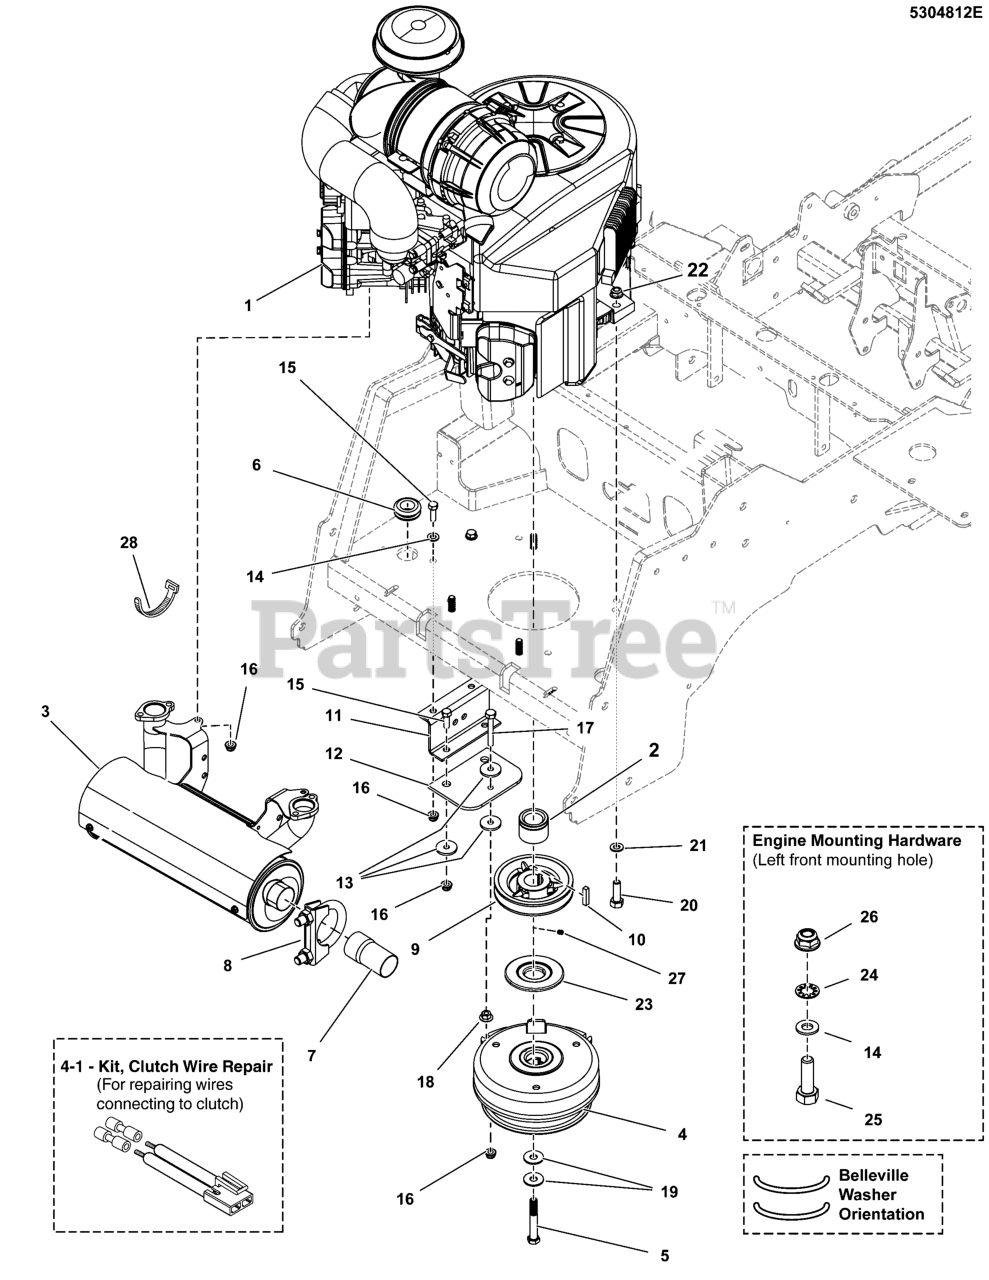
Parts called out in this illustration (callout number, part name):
2	SPACER, 1.13 X 1.75 X 1.35, CZ
3	MUFFLER (Purchase from Engine Manufacturer)
4	CLUTCH, 250 FT-LBS, WATER GUARD
4-1	KIT, CLUTCH WIRE REPAIR
5	BOLT, CRANKSHAFT, 7/16-20 X 3-1/4, GD 8
6	GROMMET, 7/8"ID, 1/4" THICK STK
7	TAIL PIPE EXTENTION, 1.78"ID X 5" LG
8	CLAMP, TAILPIPE, 1-7/8"
9	PULLEY, 4.75 OD X 1-1/8 BORE, BC-48
10	KEY, 1/4 SQ X 1-1/4
11	ANCHOR, CLUTCH, IS600-IS700 - BLK
12	CLUTCH ANCHOR PAD
13	WASHER, .34 X 1.25 X 10 GA
14	WASHER, 5/16" SAE
15	BOLT, 5/16-18 X 1 GD5 CZ
16	NUT, 5/16-18 HEX NYLOCK FLANGE
17	BOLT, 5/16-18 X 2-1/4 TFL, GD5 YZ
18	NUT, 5/16-18 HEX SERRATED FLANGE (LARGE)
19	BELLEVILLE WASHER 1.1875 X .442 X .089
20	BOLT, 3/8-16 X 1-3/4" GD5 CZ
21	WASHER, 3/8 SAE
22	NUT, 3/8 - 16 HEX NYLOCK FLANGE
23	WATER GUARD, WARNER C 250 FT-LBS CLUTCH
24	WASHER, 5/16 INT. TOOTH LOCK
25	BOLT, 5/16-24 X 1-3/4, GD8, PHOS
26	NUT, 5/16-24, TOP LOCK FLANGE, GD8 PHOS
27	SET SCREW, 5/16-18 X 3/8, KNURL (SV)
28	TIE,SELF-LOCKING, 6"
